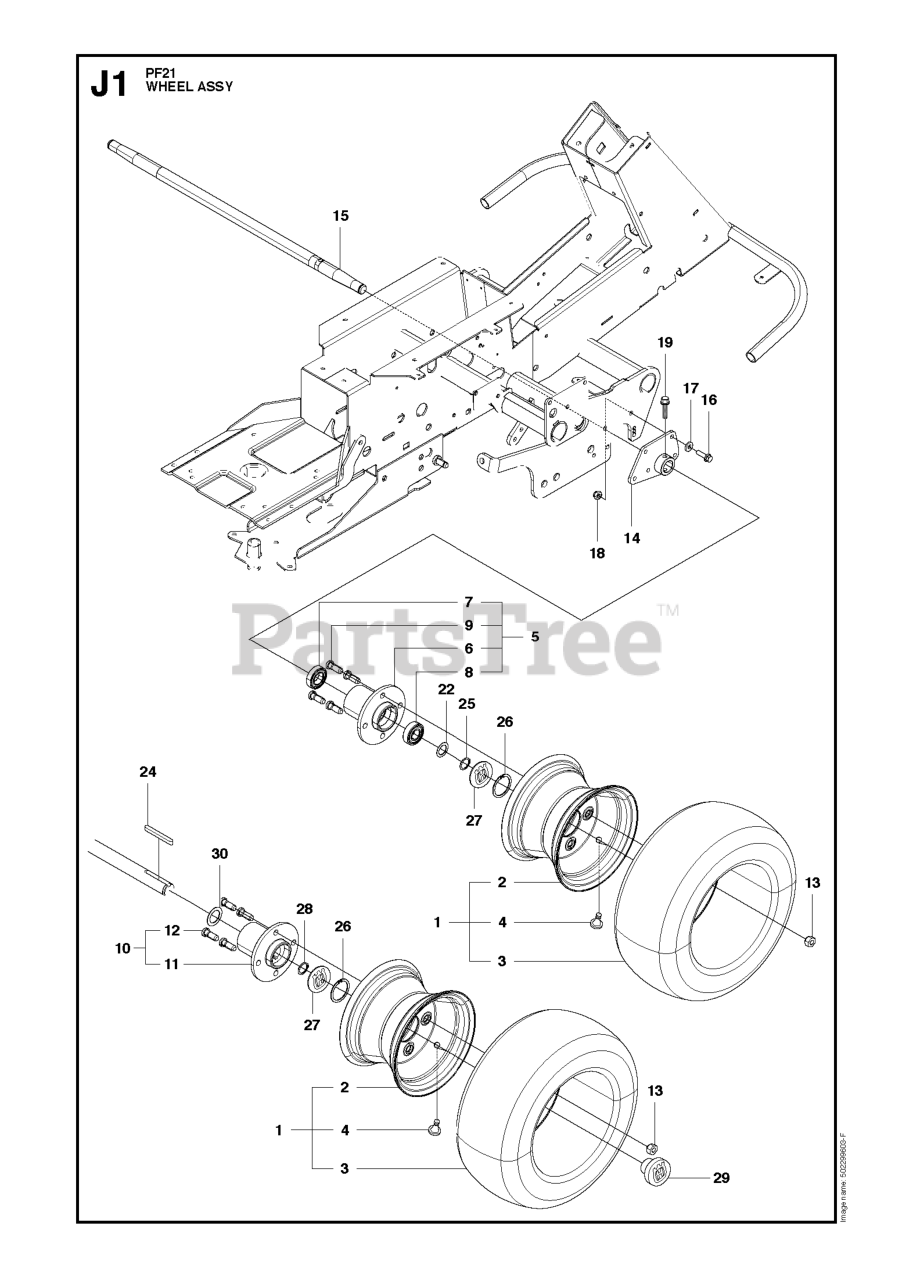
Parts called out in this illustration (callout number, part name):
3	TIRE
7	Ball Bearing 6005-2rs
8	BALL-BEARING 6204-2RS
16	BOLT
17	WASHER BRB 8.4X17
18	LOCKNUT M8
19	BOLT FLANGE - M8X40\
25	RETAINING RING SGA 20
26	RETAINING RING SGA 25
29	COVER
